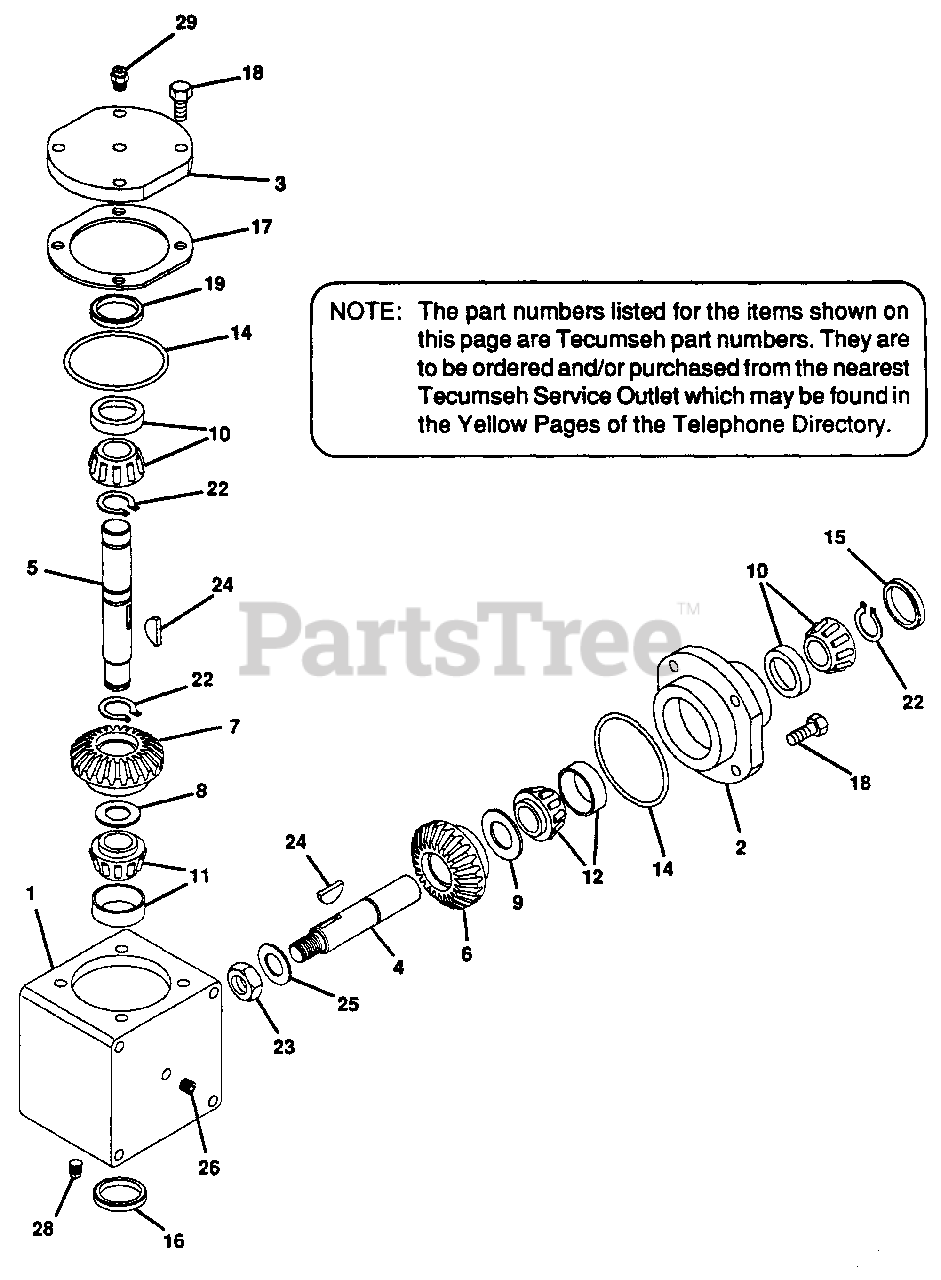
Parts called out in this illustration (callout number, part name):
1	HOUSING, RIGHT ANGLE DRIVE
2	CAP, RETAINER
3	CAP, RETAINER
4	SHAFT, INPUT (5.38" LONG)
5	SHAFT, OUTPUT (7.656" LONG)
6	GEAR, SPIRAL BEVEL (27 TEETH)
7	GEAR, SPIRAL BEVEL (18 TEETH)
8	SHIM (1-1/2" O.D. X 1-1/64" I.D. X .002 THICK)
9	SHIM (2.000" O.D. X 1.531" I.D. X .002 THICK)
10	BEARING & CUP ASSY
11	BEARING & CUP ASSY
12	BEARING & CUP ASSY.
14	"O" RING
15	SEAL, OIL
16	SEAL, OIL
17	SHIM,CAP RETAINER
18	SCREW, HEX HEAD, SEMS, 5/16-18 X 1
19	RING, LOAD
22	RING, RETAINING
23	JAM NUT, 3/4-16
24	KEY, WOODRUFF
25	WASHER, FLAT
26	PLUG, PIPE 1/4-18
28	PLUG, PIPE 1/8-27
29	VALVE, RELIEF
